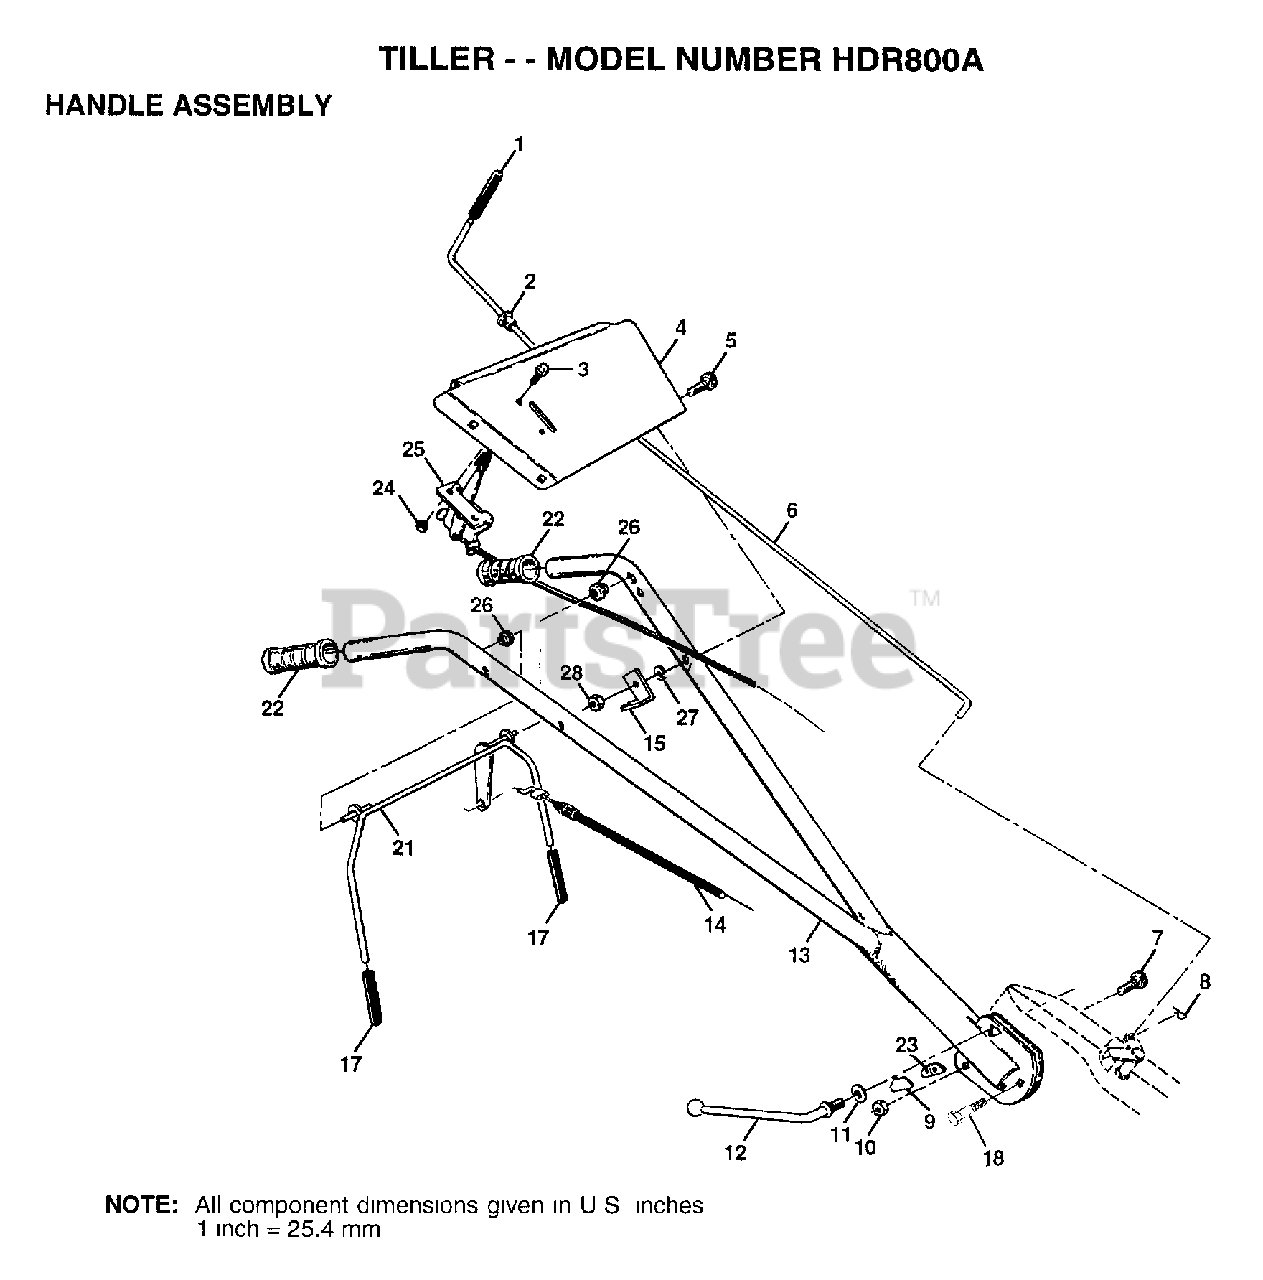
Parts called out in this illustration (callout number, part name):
1	GRIP TI
2	BUSHING
3	SCREW.PNHD.10-24
4	BRACKET.HDLE.TILL
5	BOLT CARRIAGE CRT
6	ROD SHIFT CRT
7	BOLT D
8	RETAINER M
9	LOCK CRT
10	LOCKNUT
11	WASHER CRT
12	LEVER LOCK CRT
14	CABLE.CLUTCH.Z-BE
15	BRACKET.CLUTCH.CA
17	GRIP BAR CRT
18	BOLT PIVOT
21	BAR.ASM.CNTRL.VPL
22	"GRIP,HANDLE"
23	LOCK.HANDLE
25	"CONT,THROTTLE"
26	GROMMET.HANDLE.V-
27	LOCKWASHER
28	NUT
